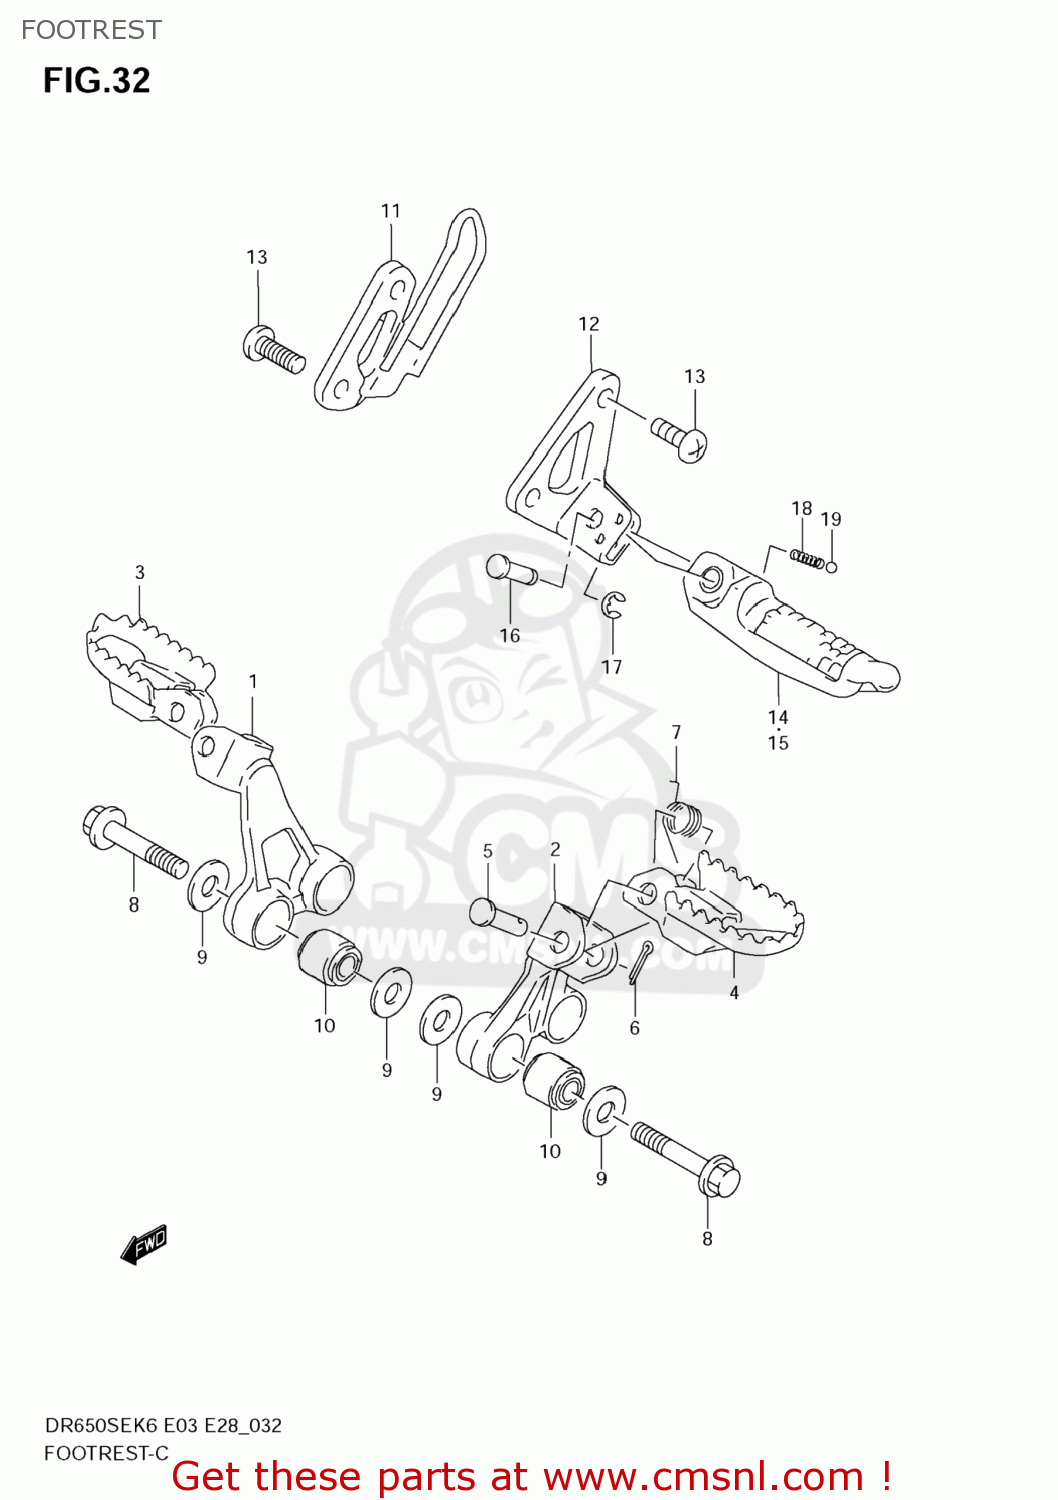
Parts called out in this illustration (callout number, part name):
1	BRACKET,FR FOOTREST,R
2	BRACKET,FR FOOTREST,L
3	FOOTREST,FRONT,RIGHT
4	FOOTREST,FRONT,LEFT
5	PIN
6	PIN
7	SPRING
8	BOLT(10X50)
9	WASHER(10.1X23X2.3)
10	BUSH(10.2X25X19)
11	BRACKET,PILLION FOOT,R(BLACK)
12	BRACKET,PILLION FOOT,L(BLACK)
13	BOLT(8X20)
14	BAR,PILLION FOOTREST,R
15	BAR,PILLION FOOTREST,L
16	PIN
17	E RING
18	SPRING
19	BALL
